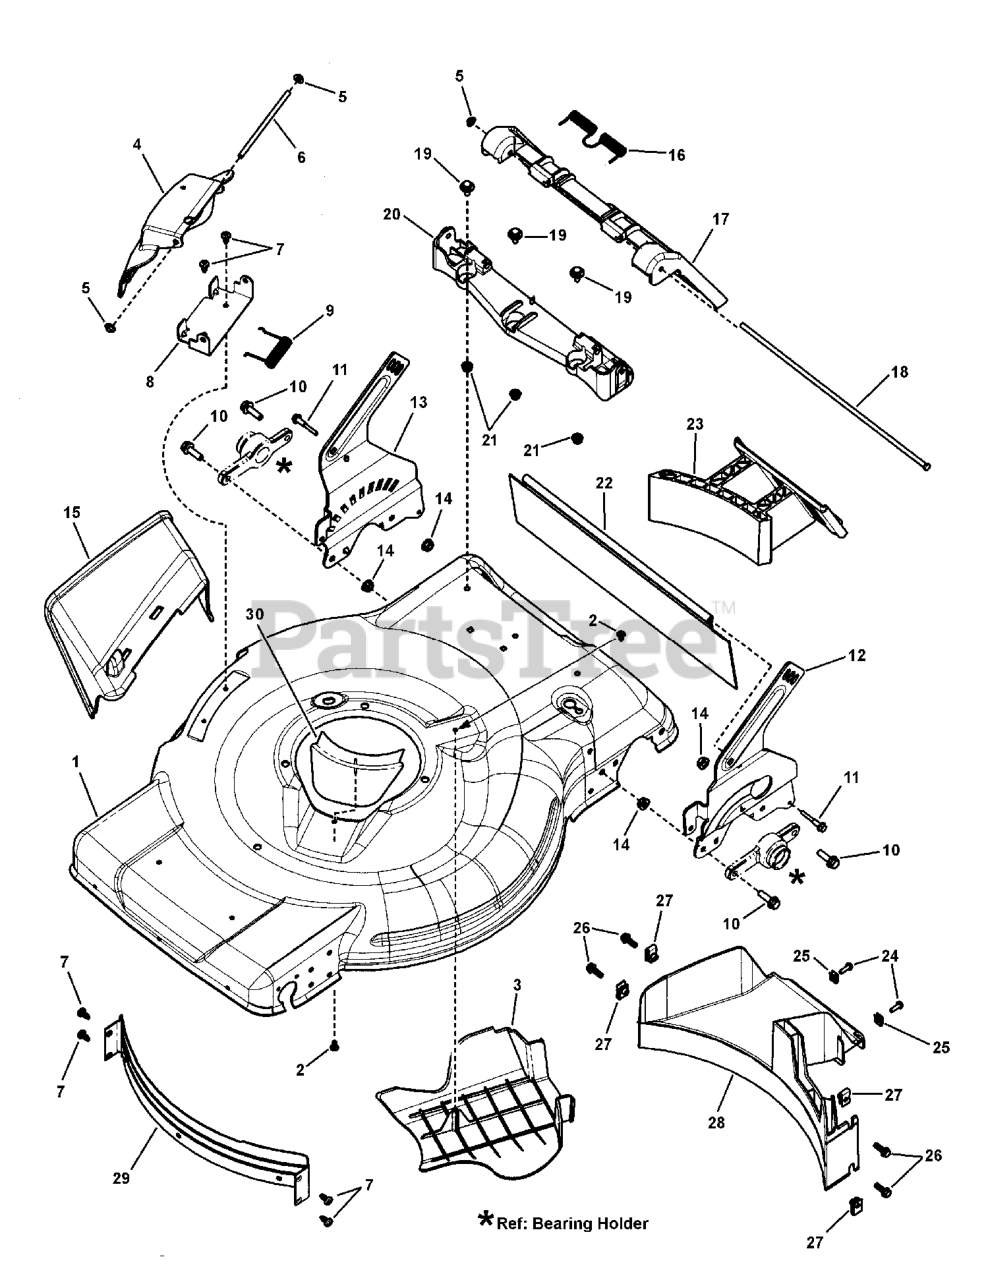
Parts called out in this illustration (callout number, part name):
1	DECK, 22", RWD, NON ES
2	SCREW, ROUND WASHER HEAD TORX, HI-LO
3	COVER, BELT DRIVE, REAR
4	COVER, MULCHING
5	PUSHNUT, 1/4
6	ROD, PIVOT
7	TORX ST, 1/4-20 X .550
8	BRACKET, CHUTE
9	SPRING, TORSION, CHUTE
10	HFLB, 5/16-18 X 1 YZ
11	BOLT, DRAG SHIELD, 1/4 - 20 X 1.5
12	BRKT, REAR WHEEL, LH, QUICK ADJUST
13	BRKT, REAR WHEEL, RH, QUICK ADJUST
14	FLN, 5/16-18 YZ
15	CHUTE, SIDE DISCHARGE, WBM, 22"
16	SPRING, TORSION, REAR DOOR
17	REAR DISCHARGE DOOR
18	ROD, PIVOT, REAR DOOR
19	HHSTS, 1/4-20 x 5/8"
20	REAR DISCHARGE DOOR HINGE
21	HFLN, 1/4-20
22	GUARD, REAR 22"
23	PLUG, MULCHING, 22" DECK
24	HWFST, 10C X 5/8
25	NUT, RETAINER SPEED #10C W/EXT
26	HFLB, 1/4-20X3/4
27	NUT, 1/4 TINNERMAN
28	REAR, BAFFLE REAR WHEEL DRIVE WBM
29	BAFFLE, FRONT
30	SHIELD, DEBRIS, FRONT
